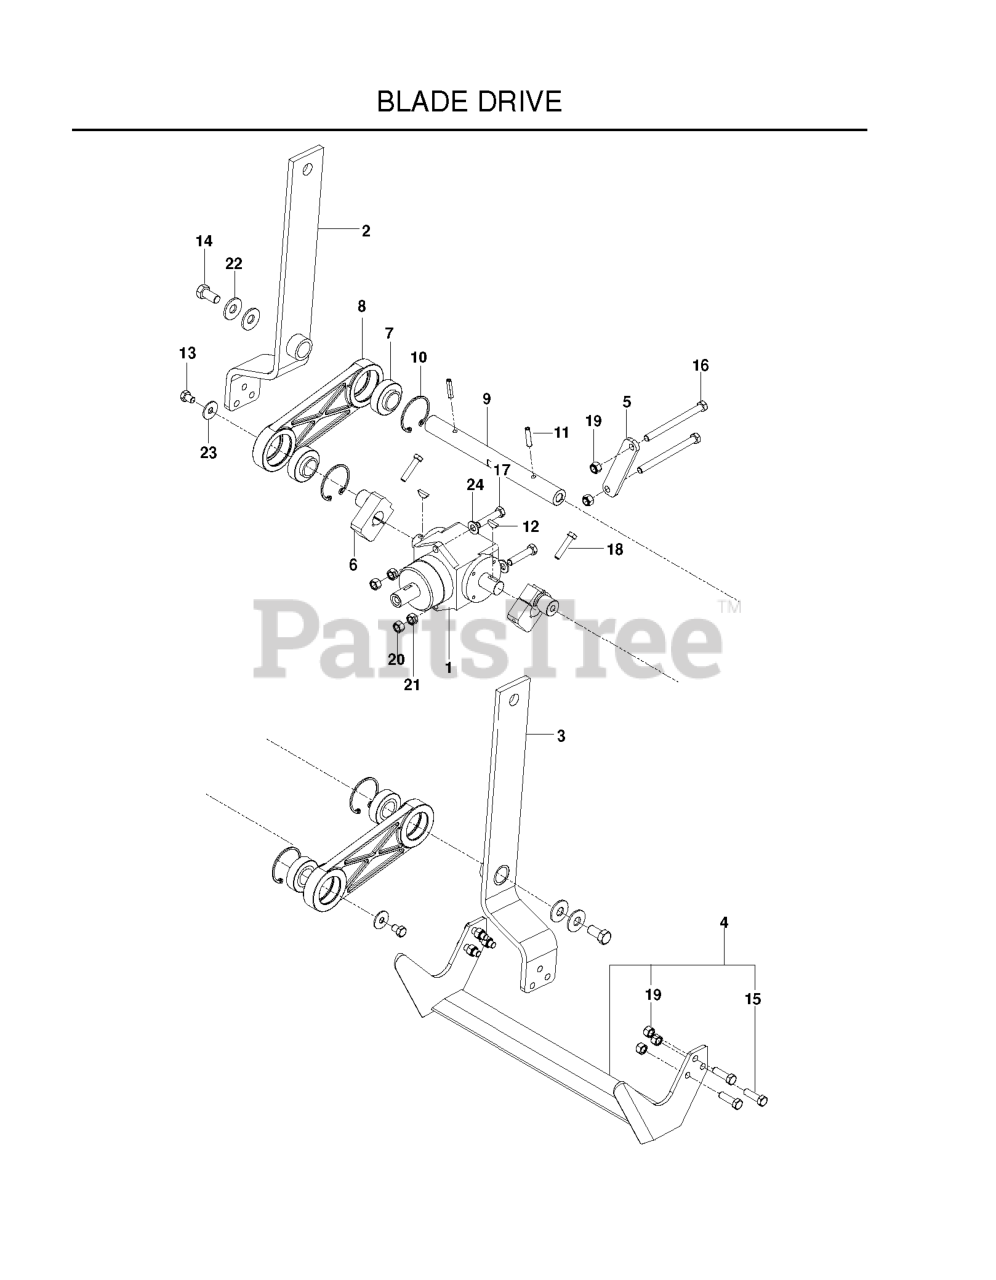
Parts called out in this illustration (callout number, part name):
1	GEAR BOX
2	BLADE ARM R.H., BLACK
3	BLADE ARM L.H., BLACK
4	KIT CUTTING BLADE 18" SOD CUT
5	STRAP T-BOX BLACK
6	SNAP RING 52MM
7	BEARING-ECC LOCK W/COLLAR
8	LINK - CONNECTING
9	SHAFT - BLADE ARM
11	SPIRAL PIN 1/4 DIA X 1.25
12	KEY, #9 WOODRUFF
13	BOLT .375 X .5
14	HHCS 1/2-13 X 1
15	HCS 3/8-16 X 1-1/4 GR 8 ZD
16	HCS 3/8C X 4 1/2
17	HCS 3/8-24
18	CAPSCREW 5/16 X 1/1/2 HEX HEAD
19	NUT 3/8-16 NYLOC
21	NUT 3/8F CENTERLOCK
22	SPRING WASHER - .50
23	SPRING WASHER - .38
24	WASHER 3/8 SAE FLAT
